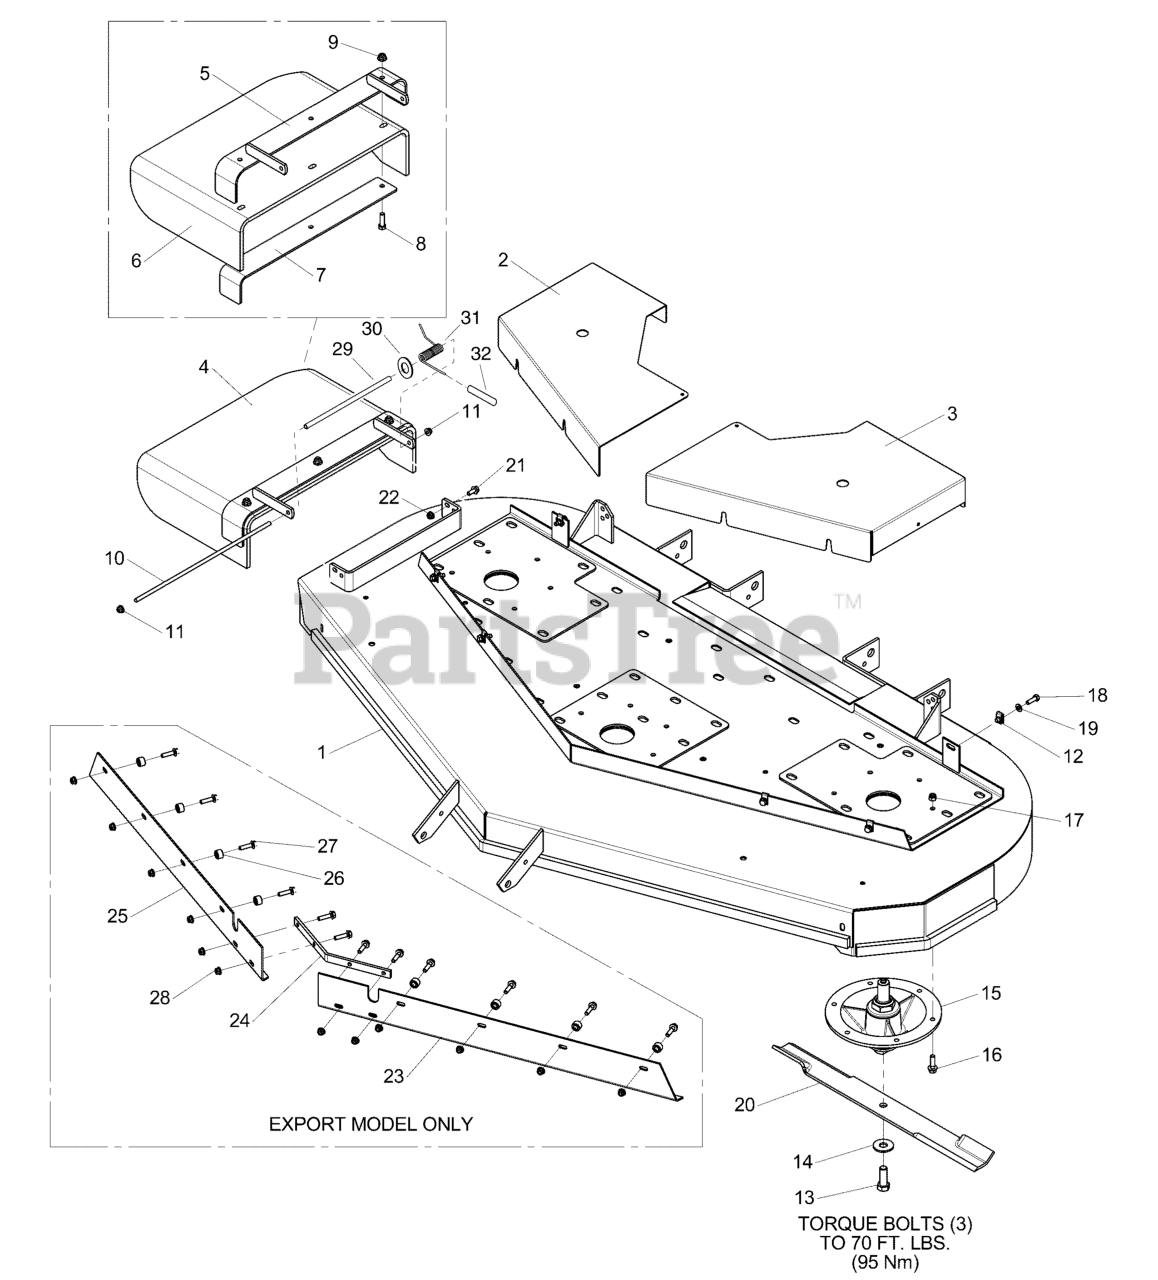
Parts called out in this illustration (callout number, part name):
2	GUARD, 72", RH
3	GUARD, 72", LH
4	RUBBER CHUTE ASSEMBLY
5	CHUTE FRAME
6	CHUTE, DISCHARGE, RUBBER, 61/72, BENT
7	SUPPORT, DISCHARGE CHUTE
8	BOLT, 3/8-16 X 1-1/4" GD5 CZ
9	NUT, 3/8-16 HEX NYLOCK FLANGE
10	ROD, MOUNT, CHUTE, 61"
11	NUT, 5/16-24 HEX NYLOCK FLANGE
12	BODY CLIP, 5/16-18-7GA MATERIAL
13	BOLT, 5/8-11 X 1-3/4 GR8
14	WASHER, 5/8" GRADE 8, YZ
15	SPINDLE ASSEMBLY
16	BOLT, 3/8-16 X 1-1/4", FLANGE
17	NUT, 3/8-16 HEX NYLON LOCK
18	BOLT, 5/16-18 X 1"
19	WASHER, 5/16" SAE
21	BOLT, 5/16-18 X 3/4 GD5
22	NUT, 5/16-18 HEX NYLOCK FLANGE
23	BLOWOUT BAFFLE, LH
24	BAFFLE, REINFORCEMENT - BLK
25	BLOWOUT BAFFLE, RH
26	SPACER, .39 X .75 X .50, CZ
27	BOLT, 5/16-18 X 3/4" FLANGE
28	NUT, 5/16-18 HEX NYLOCK FLANGE
29	TUBE, 1/2 X 3/8 X 10.75 BLACK POLY
30	WASHER, 5/16 FENDER
31	SPRING, TORSION
32	CAP, PROTECTOR, .120 ID
